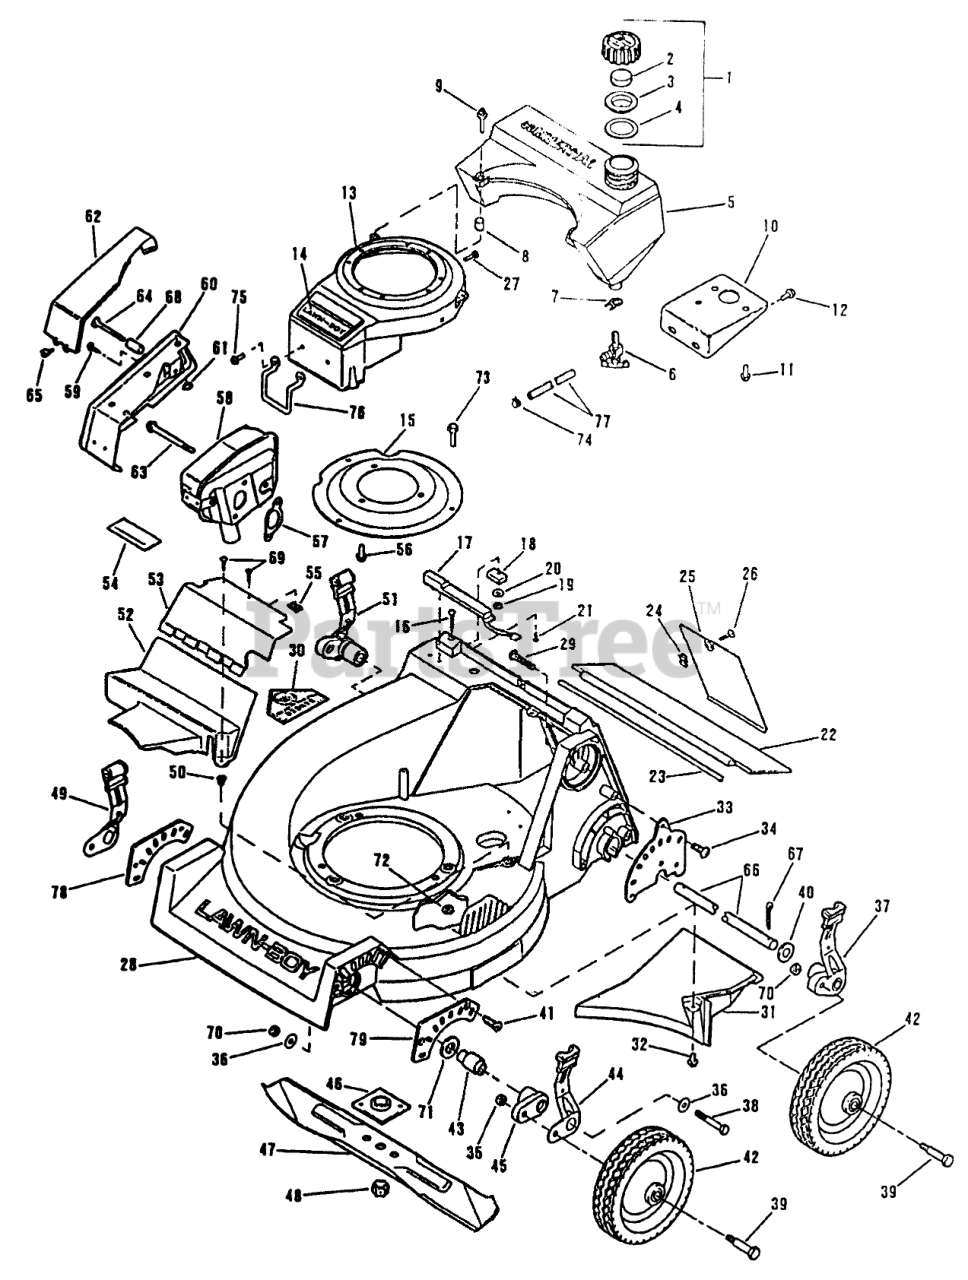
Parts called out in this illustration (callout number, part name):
1	CAP AY - F/OIL SM
2	BAFFLE - FOAM SM
3	Cover
4	GASKET-FUELCAP SM
5	Fuel Tank
6	VALVE&SCREEN SM
7	CLAMP - HOSE S
8	Spacer
9	SCREW - SEMS SM
10	Fuel Tank Mounting Bracket
11	SCREW-HH
12	SCREW HEX WASH SM
13	SHROUD & APPL S
14	APPLIQUE SM
15	PLATE S
16	SCREW
17	SWITCH ASSEMBLY
18	MAGNET ASSY
19	NUT
20	LOCKWASHER #10
21	SCREW-STAINLESS
22	SHIELD-TRAILING-21
23	ROD ADVANCE
24	SPEED NUT LARSON
25	DOOR-ACCESS ELECT.
26	SCREW-CROSS RECESS
27	SCREW SM
28	Housing Assembly
29	BOLT - RIBBED NECK
30	Decal
31	CHUTE BAFFLE NYL
32	Screw
33	PLATE HGT CMS
34	SCREW-BUTTON HEAD
35	NUT-JAM, LOCKING
36	WASHER PLAIN
37	HT. ADJ. ARM AY-L
38	SCREW - HEX HEAD
39	BOLT-WHEEL-SHOULDR
40	WASHER-PLAIN
41	SCREW,FLAT HEAD
42	WHEEL/TIRE ASM
43	BUSHING,FRT HT ADJ
44	KNOB & SPRING CMS
45	ARM HGT ADJ BLACK
46	PLATE AND COLLAR ASM
47	21" Blade
48	NUT-BLADE
49	KNOB & SPRING CMS
50	NUT-CLIP
51	HT. ADJ. ARM AY-R
52	COVER-DRIVE-LOWER
53	COVER-UPPER
54	DECAL
55	NUT-SPEED
56	SCREW SM
57	GASKET - EXH SM
58	Muffler
59	SCREW S
60	GUARD AY-MUFFLER
61	NUT-PUSH
62	COVER-MUFFLER
63	SCREW-SEMS
64	SCREW SM
65	SCREW SM
66	OBS ROD HGT ADJ R GLM
67	CotterPin
68	SPACER S
69	SCREW S
70	NUT
71	WASHER, PLAIN
72	NUT-LOCK F
73	SCREW-HH
74	HOSE CLAMP SM
75	SCREW-HEX FL SM
76	GUARD-SPK.PLUG.SM
77	GAS LINE S
78	RH PLATE HEIGHT ADJ LB
79	LH PLATE HEIGHT ADJ LB
